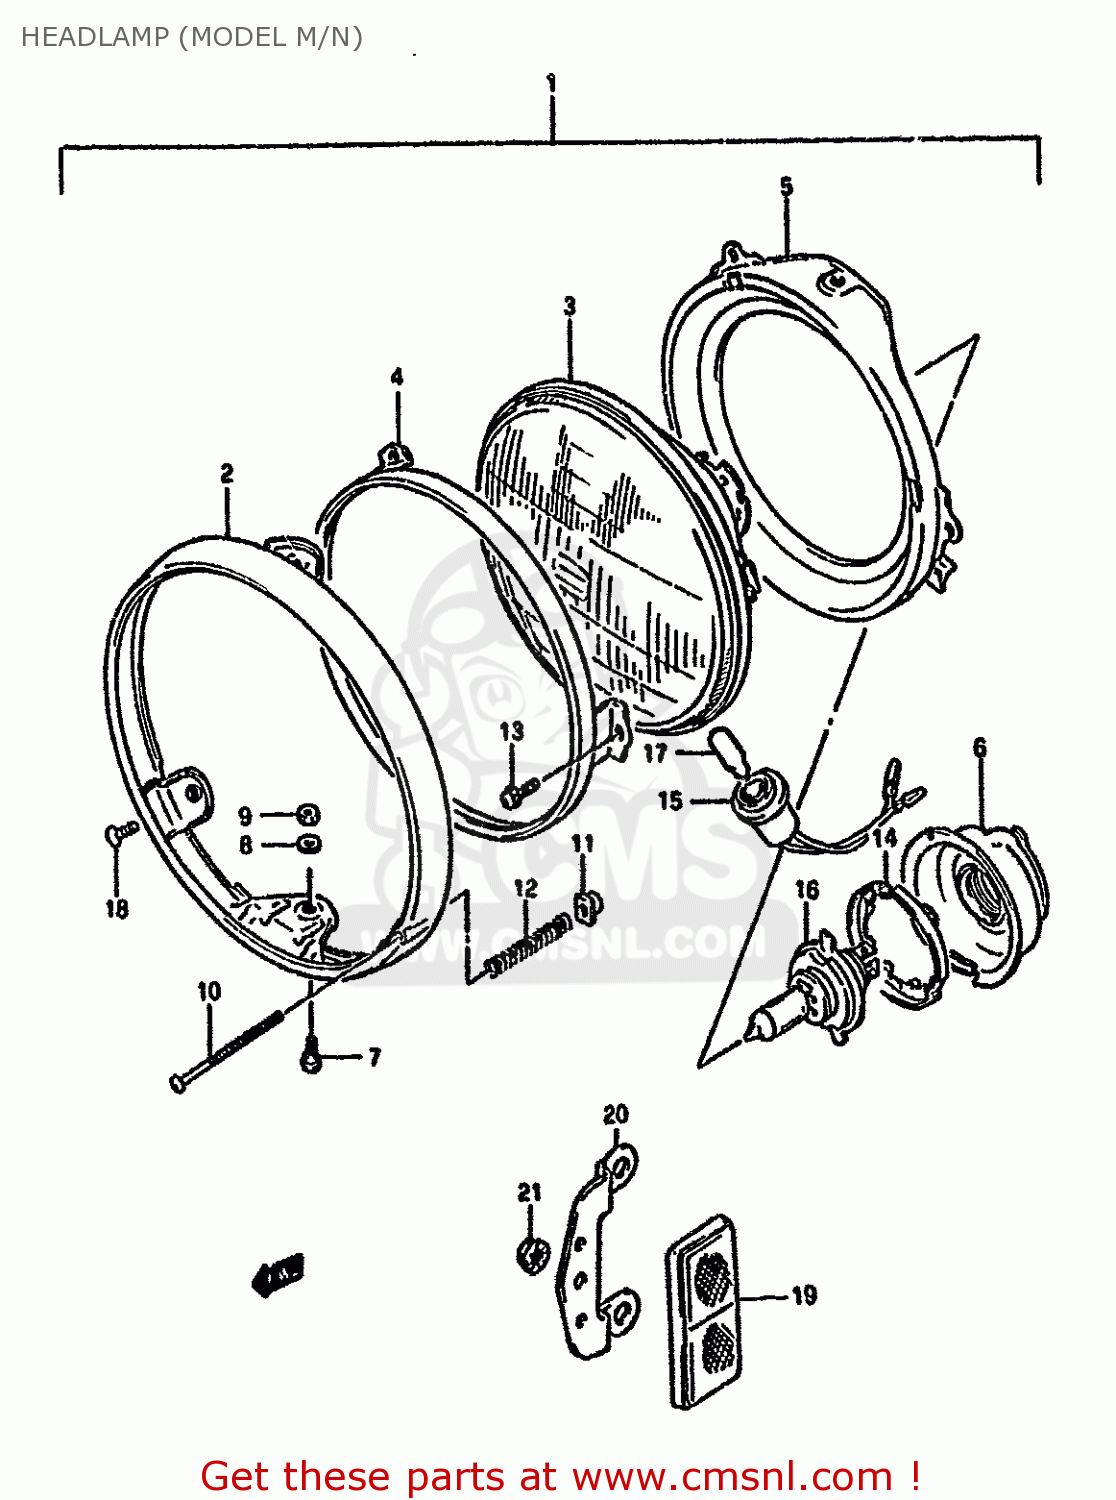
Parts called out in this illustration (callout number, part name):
1	HEADLAMP ASSY
2	RIM,HEADLAMP
3	LAMP UNIT
4	RETAINING RING
5	RING
6	COVER,HEADLAMP SOCKET
7	H/LAMP LENS UNIT FITING SCRE
8	LOCK WASHER
9	NUT
10	SCREW,HEADLAMP ADJUST
11	NUT
12	SPRING,ADJUSTING
13	SCREWM4X0.7X10
14	SETTING,BULB
15	SOCKET
16	BULB(12V60/55W,H4)
17	BULB(12V4W)
18	SCREW 5X12
19	REFLEX REFLECTOR,FR SIDE
20	BRACKET,FRONT SIDE REFLECTOR
21	NUT
